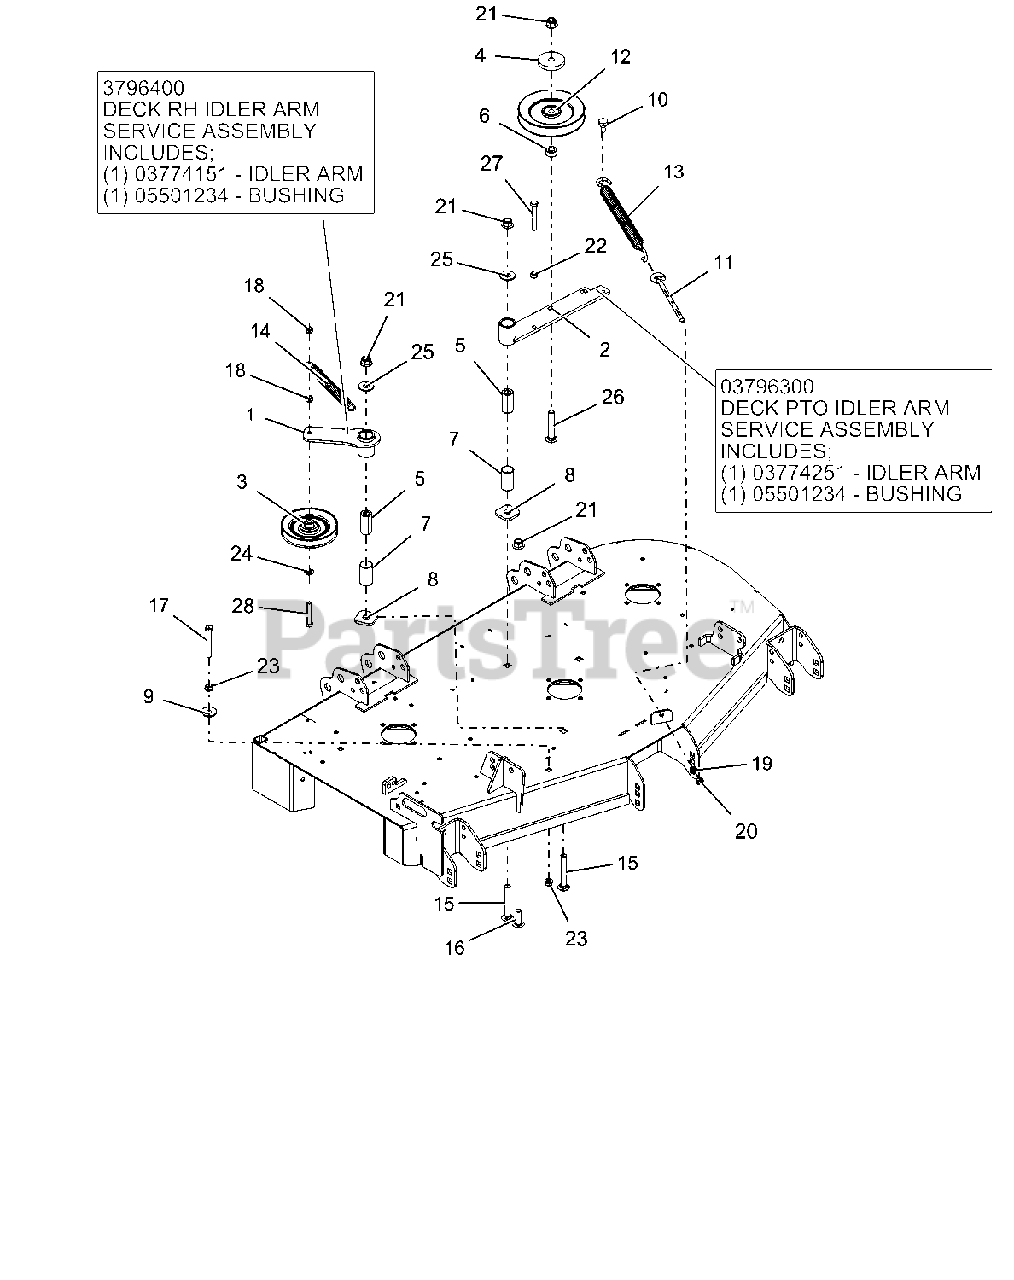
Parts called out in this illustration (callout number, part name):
1	ASM, IDLER ARM (DECK)
1	WMT, IDLER ARM - BLACK
1	BSHG, 1.00X1.125X1.937
2	WMT, IDLER ARM
2	ASM, IDLER PIVOT ARM (PTO)
2	BSHG, 1.00X1.125X1.937
3	IDLER, V-5.00"
4	CAP, IDLER BEARING SEALING
5	BSHG, SPCR .502X.997X2.03 PM
6	BSHG, SPCR .502X.997X.50 PM
7	BSHG, 1.00X1.125X1.937
8	WSHR-FLT .640X1.75X.250
9	WSHR-FL-STL .406X1.375X.135 YZ
10	BLT,SHLDR EP .38-16X.30 HEX YZ
11	BOLT, .38-16X6.00 .62 DIA EYE
12	SHV, .50"ID X 6.00"OD V-IDLER
13	SPRING, EXTENSION
14	SPRING, EXTENSION
15	@BLT-RDHDSQNK .50-13X3.50 G5YZ
16	BLT-RDHDSHSQNKFT.50-13X1.50 G5
17	@BLT-HEX .38-16X3.00 GR5 YWZC
18	@NUT-LK-CTR .38-16 YWZC
19	NUT-HEX-JAM .375-16 YWZC
20	@NUT-LK-CTR-JAM .375-16 YWZC
21	@NUT-LK-NYL-FLG .50-13 YWZC
22	@NUT-HEX .38-16 YWZC
23	@NUT-SPNLK-FLG .375-16 YWZC
24	@WSHR-FL-STL.406X.812X.065 YWZ
25	@WSHR-FL-STL.563X1.38X.109YWZC
26	@BLT-RDHDSQNK .50-13X3.00 G5YZ
27	BLT-HEX .38-16X2.75 GR8 YWZC
28	@BLT-HEX .38-16X2.25 GR5 YWZC
